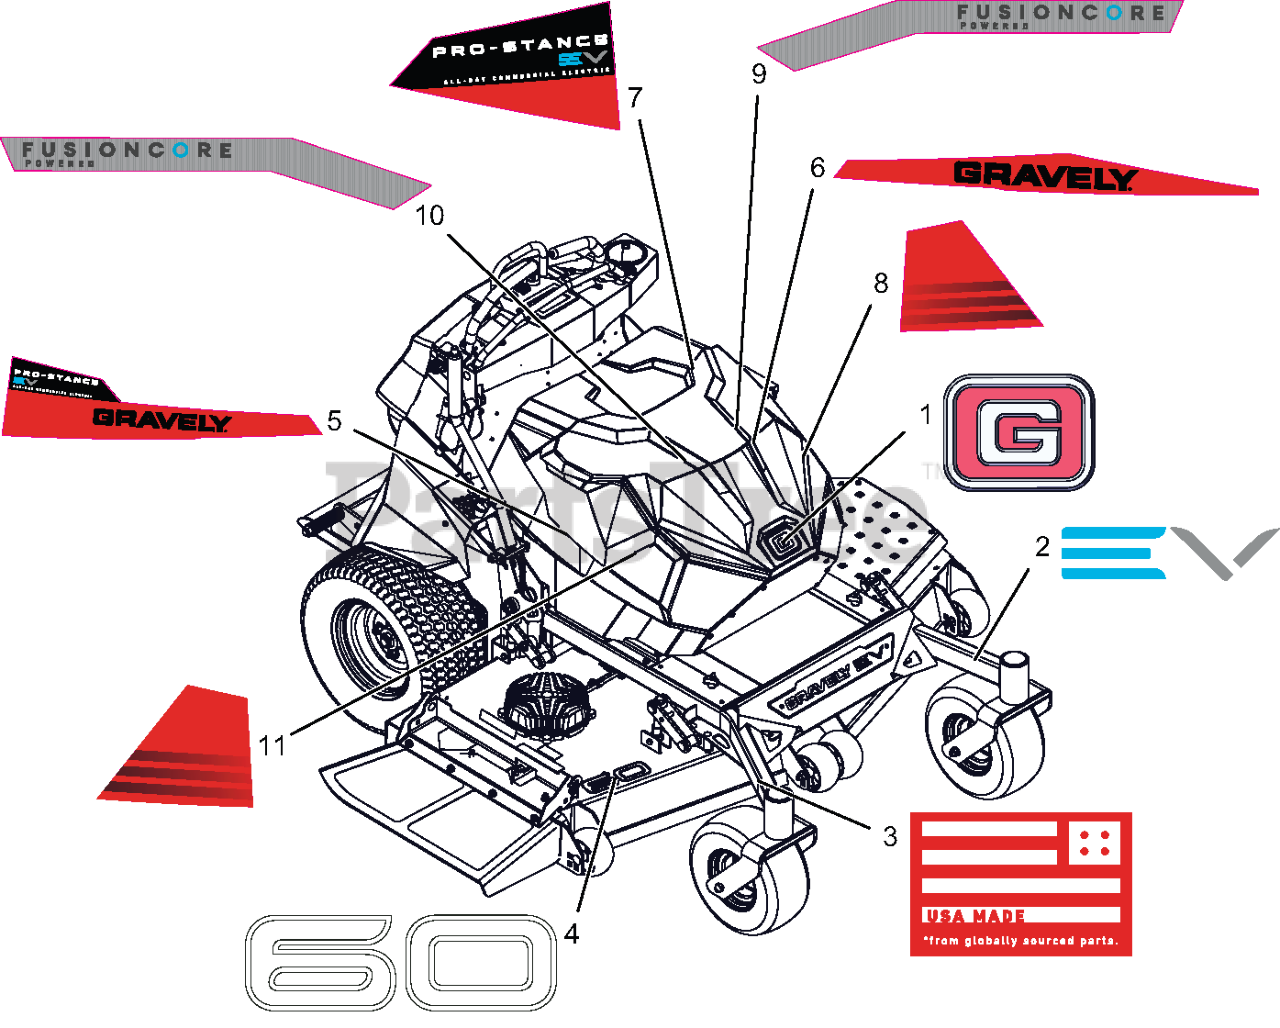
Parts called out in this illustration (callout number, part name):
1	DECAL, GRAVELY BRAND
2	DECAL, FRONT FORK
3	DECAL, USA MADE
4	DECAL, DECK - 60"
5	DECAL, RH FENDER LOWER - PSEV
6	DECAL, LH FENDER - PSEV
7	DECAL, REAR HOOD - PSEV
8	DECAL, FRONT HOOD - PSEV
9	DECAL, LH FUSIONCORE - PSEV
10	DECAL, RH FUSIONCORE - PSEV
11	DECAL, RH FENDER UPPER - PSEV
